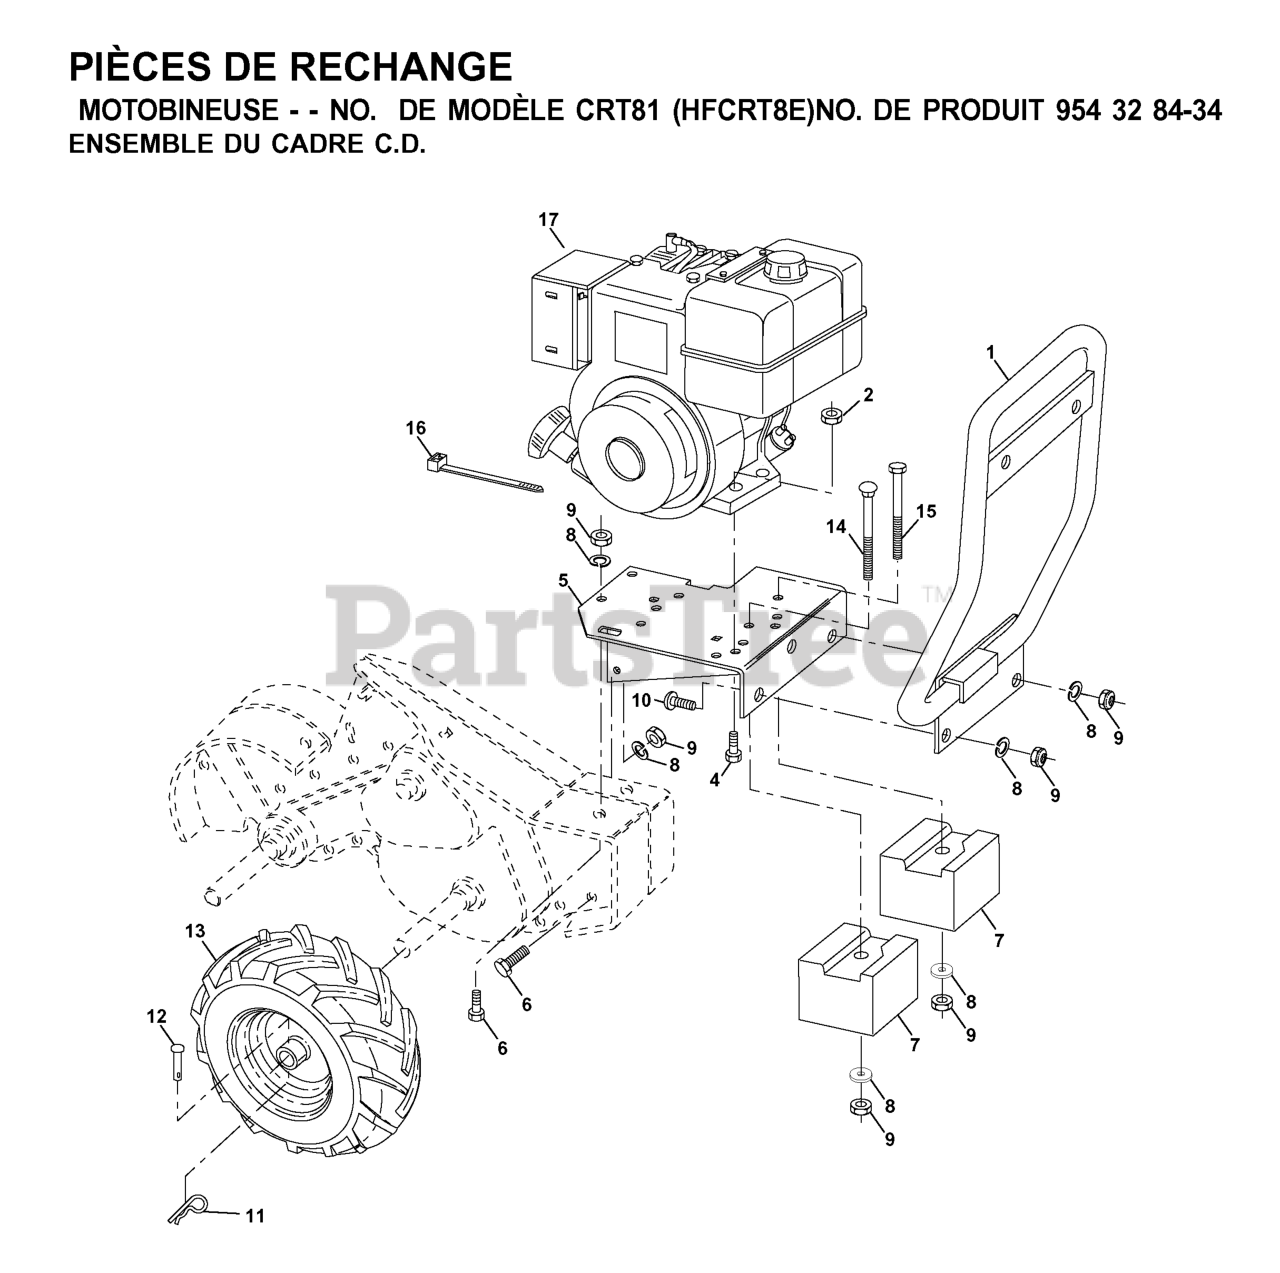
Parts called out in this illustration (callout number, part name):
2	LOCKNUT-FLANGE 5/16-18
4	BOLT, HEX 5/16-18X1-3/4
5	ENGINE BRACKET
6	BOLT
7	COUNTER WEIGHT RH
8	WASHER, LOCK 3/8
9	NUT.HEX.3/8-16UNC
10	BOLT D
11	SPRING TI
13	TIRE.16X4-8.CHEVRON.TILLER
14	Bolt, Carriage 3/8-16 x 4-1/2
15	BOLT, HEX 3/8-16X4-1/2
16	TIE CABLE CRT
532124366	RIM
532124718	VALVE STEM LT
